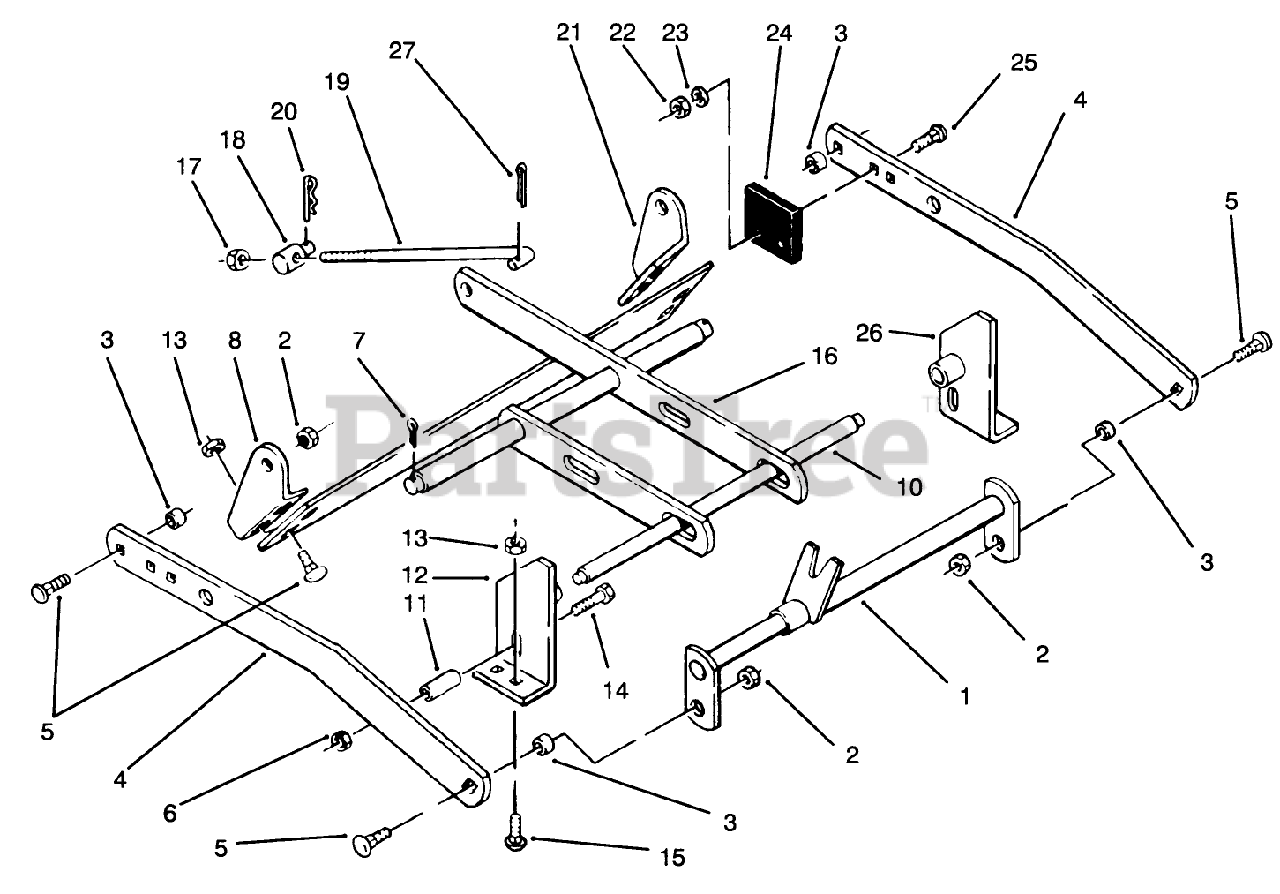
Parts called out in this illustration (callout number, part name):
1	Hitch
2	LOCKNUT-FLANGE
3	SPACER
4	Bar Draft
5	BOLT-CARR
6	Nut
7	PIN-COTTER
8	Bracket-R.H.
10	Front Shaft
12	Bracket-R.H.
13	NUT-LOCK, NI
14	BOLT-CARR
15	BOLT-CARR
16	Leveler
17	NUT-LOCK, NI
18	TRUNNION-LIFT
19	Rod-Lift
20	Hairpin
21	Bracket-L.H.
22	NUT-LOCK, NI
23	WASHER-FLAT
24	BUMPER
25	SCREW-CARR
26	Bracket-L.H.
27	PIN-COTTER
